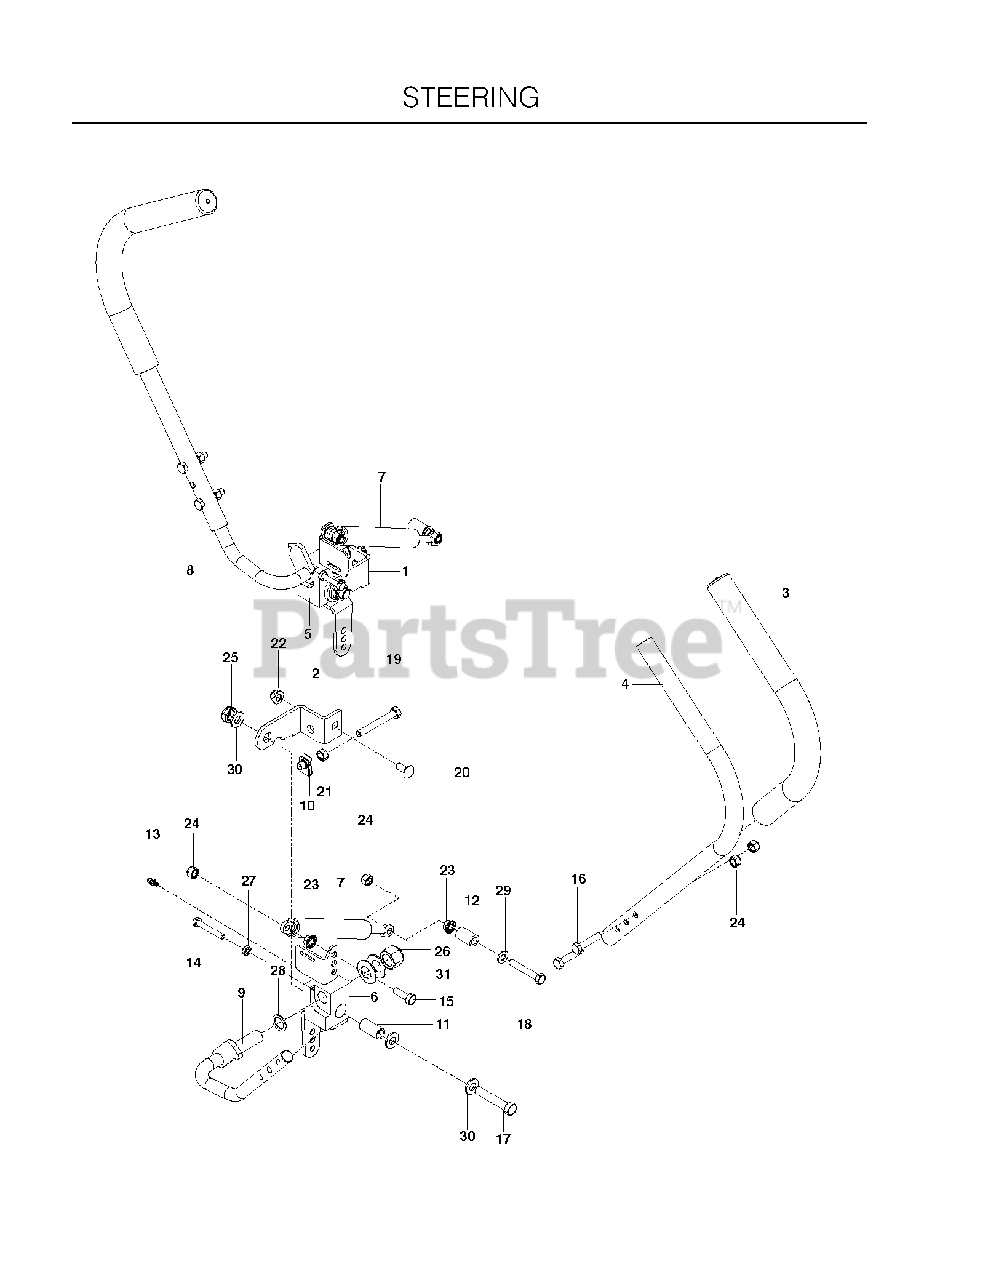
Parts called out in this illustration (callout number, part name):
1	FORWARD STOP RH
2	FORWARD STOP LH
4	LEVER UPPER
5	PIVOT RH (PLATED)
6	PIVOT LH (PLATED)
7	DAMPENER, DUAL ACTION
8	LEVER.PLATED.RH
9	LEVER PLATED LH
10	U-CLIP 5/16-18 NUT RETAINER
13	ZERK, 3/16, DRIVE IN
14	BOLT 1/4C X 1 3/4
15	HCS 5/16C X 1
16	CAPSCREW 5/16 X 1/1/2 HEX HEAD
17	HCS 1/2C X 2 3/4
18	HCS 5/16-18X2
19	HCS 5/16-18 X 2 1/2 TPBLT
20	BOLT 5/16C X 3/4" CARRIAGE
21	NUT 5/16C HEX
22	5/16-18 NYLOC FLANGE NUT
23	NUT 5/16C WHIZ
24	NUT 5/16 NYLOC
25	NUT 1/2-13 HEX JM NYL
26	NUT 5/8-11 NYLOC
27	NUT 1/4-20 JAM
28	WASHER-.626IDX.056TK
29	FLAT WASHER 5/16 SAE
30	WASHER 1/2" FLAT
31	WASH 5/8 BEVELED DISC SPRING
